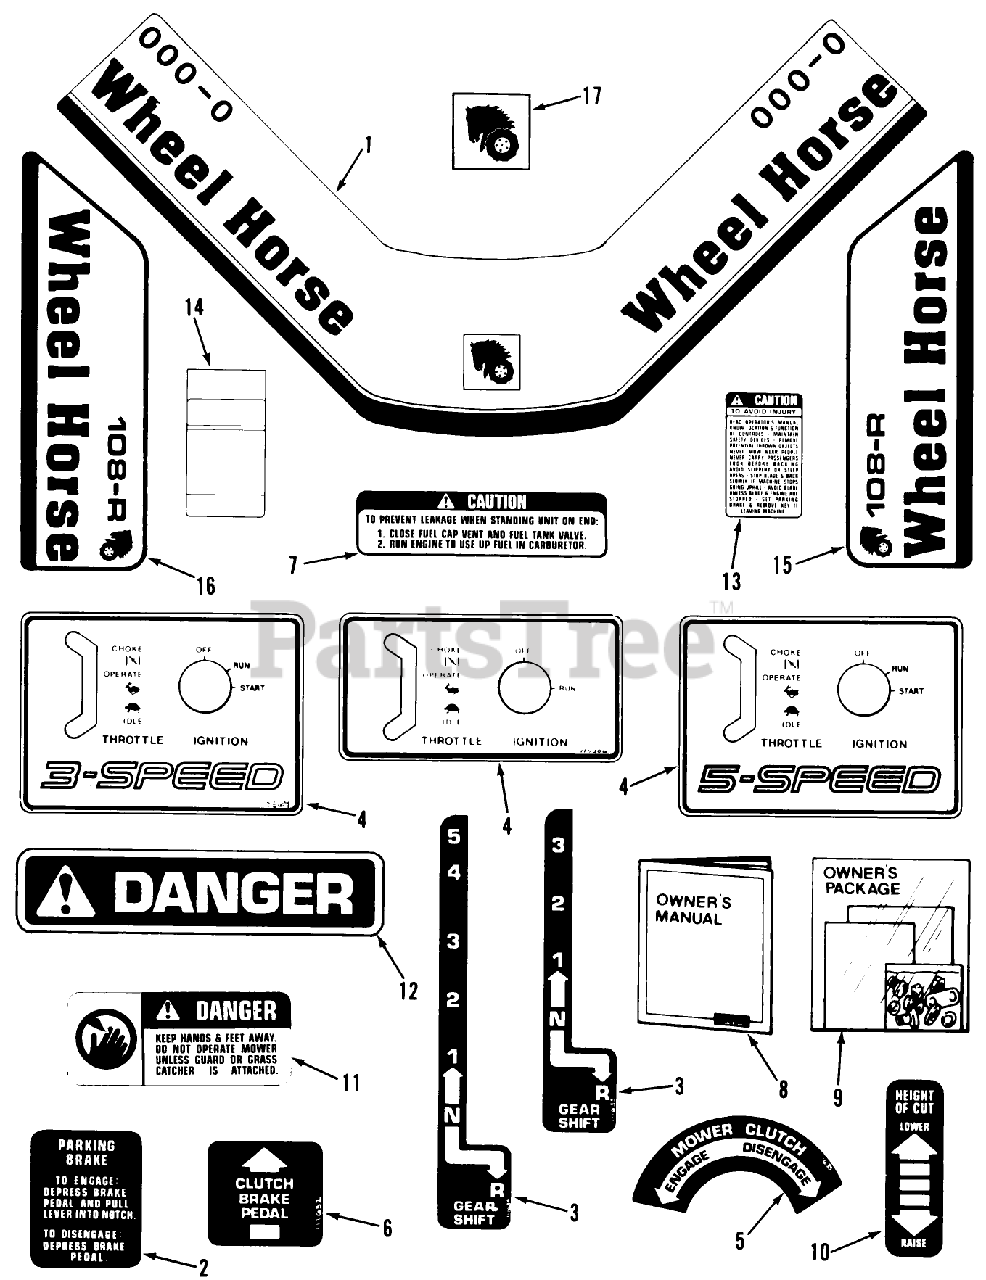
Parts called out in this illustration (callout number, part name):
6	DECAL CLUTCH & BRAKE
8	Owners Manual
10	DECAL-HOC
